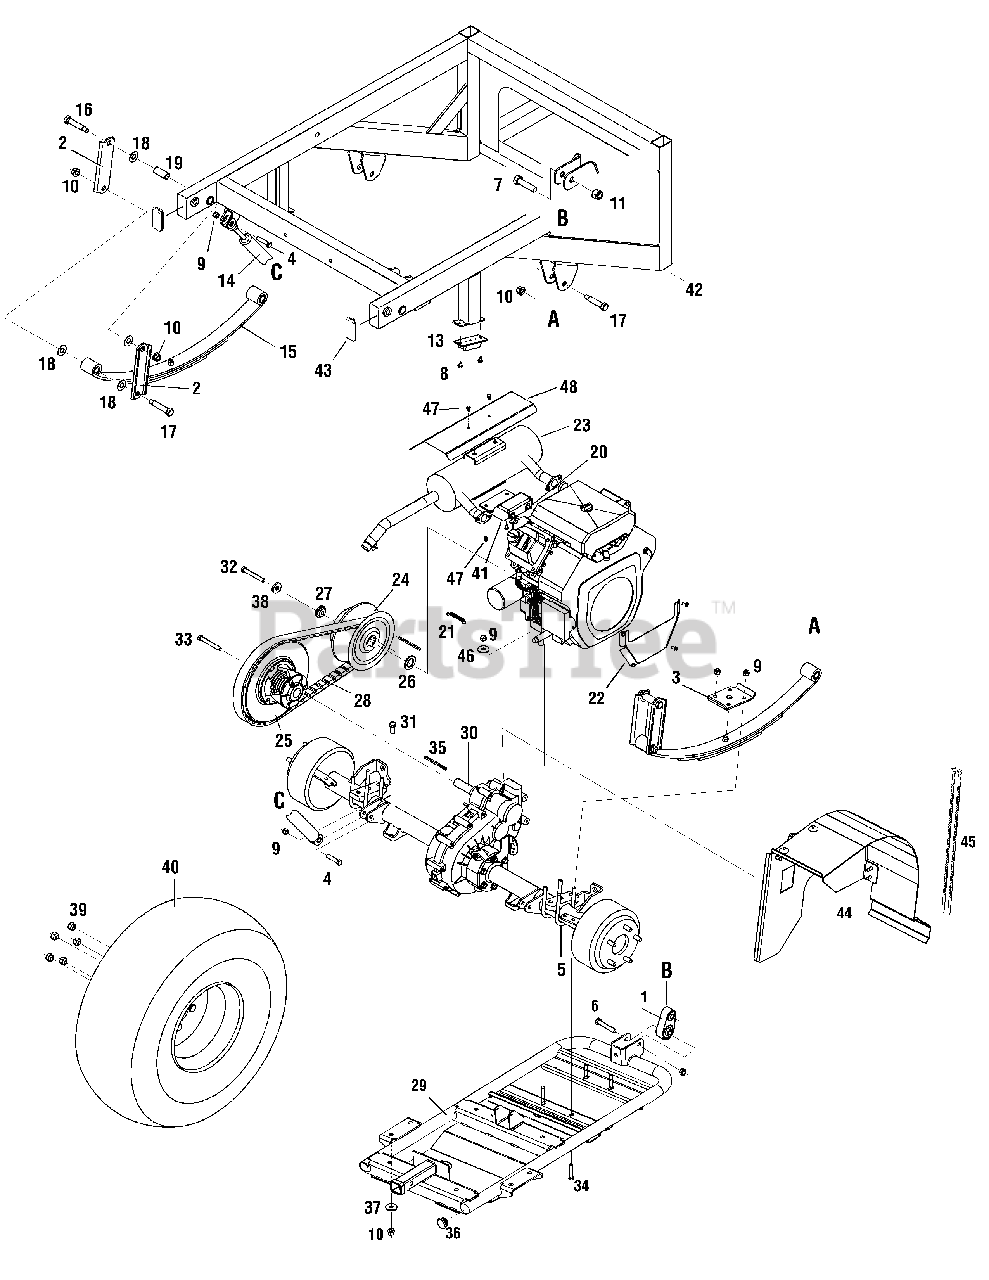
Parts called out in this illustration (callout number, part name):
1	Link Assembly
2	Plate, Shackle
3	Bracket, Spring Leaf
4	Hex Screw, 3/8-16 x 1.75
5	U-Bolt 3/8-16
6	Hex Screw, M12-1.75
7	Hex Screw, 5/8-11 x 2.5
8	Screw, Self Tapping 1/4-20
9	Locknut, Nylon, 3/8-16
10	Flange Lock Nut 7/16-20
11	Hexlock Nut, Flange, 5/8 -11
12	Hexlock Nut, M12 x 1.75
13	Bumper, Suspension
14	Shock Absorber, 2.50 Stroke
15	Spring, Leaf 4 x 2
16	Shoulder Screw, .550 x 2.29
17	Shoulder Screw, .550 x 2.13
18	Bearing, .56 ID x 1.25 OD x .06
19	Bushing, .75 OD x .562 ID x 1.75 LG
20	Screw, M8 x 1.25:20
21	Extension Spring
23	Muffler, Kohler
24	Clutch Assembly, Engine (Incl. Bearing Cap)
25	Clutch Assembly, Transmission
26	Washer, Flat, 1.03 x 1.625 X .12
27	Spacer, .39 x 1.0
28	Belt, Cogged
31	Hex Screw, 7/16-20 x 1.0
32	Hex Screw,3/8-24 x 3.00
33	Hex Screw, 1/2-20 x 2.25
34	Hex Screw,3/8-16 x 2.00
35	Key, Square 1875 x 3.25
36	Plug, Tube
37	Washer, Flat, .469 x .875 x .105
38	Washer, Flat, .531 ID x 1.25 X 1.00
39	Lug Nut, 7/16-14
40	Wheel Assembly, 25 x 11 x 10 LH
40	Wheel Assembly, 25 x 11 x 10 RH
40	Wheel Assembly, 25 x 12 x 9 Turf
41	Muffler Bracket
42	Frame Assembly
43	Tubing Plug 1.5 x 3.0
46	Washer, Flat, .406 x 1.00 x .105
47	Hex Head Screw M6 1.0:10mm
48	Kohler Heat Sheild
